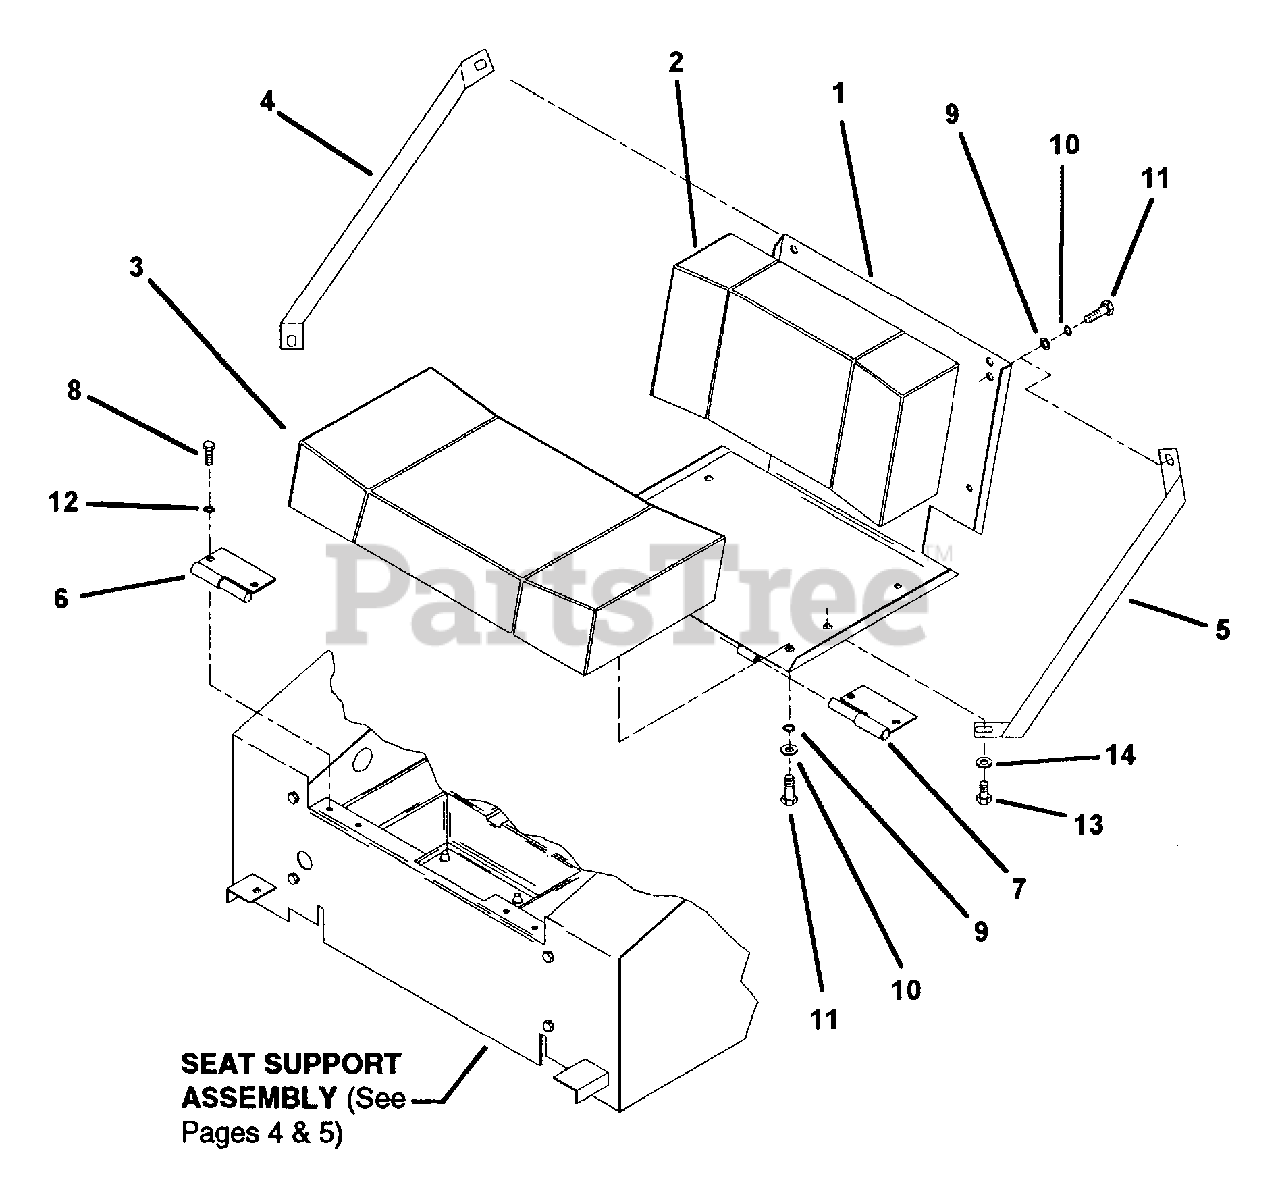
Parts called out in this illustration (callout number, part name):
1	SEAT BRACKET WELDMENT
2	CUSHION BACK ASSEMBLY
3	CUSHION SEAT ASSEMBLY
4	GUSSET, SEAT RIGHT
5	GUSSET, SEAT LEFT
6	HINGE
8	BOLT, 1/4-20 X 3/4" GR. 5
9	WASHER, FLAT STD. 5/16"
10	LOCK WASHER, 5/16" SPLIT SPRING
11	BOLT, 5/16-18 X 1" GR. 5
12	LOCK WASHER, 1/4" SPLIT SPRING
13	BOLT, 5/16-18 X 5/8" LONG LOCK
14	WASHER, 5/16 ID X 5/8 OD X .035 THK
